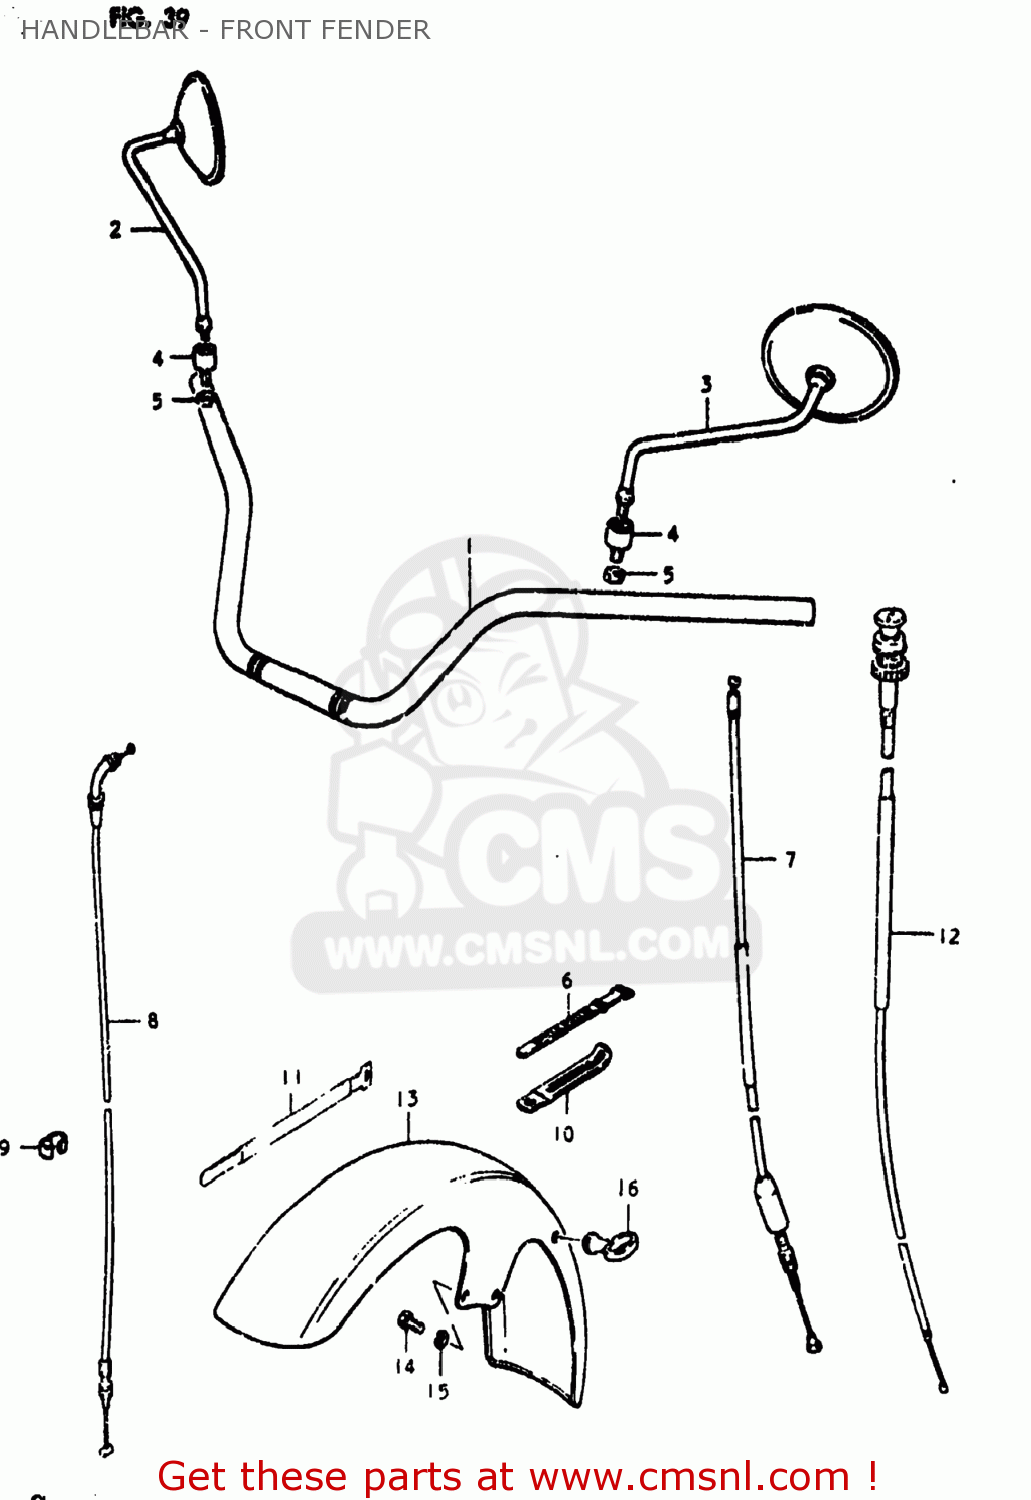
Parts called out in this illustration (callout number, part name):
1	HANDLEBAR
2	MIRROR ASSEMBLY,REAR VIEW
3	MIRROR ASSEMBLY,REAR VIEW
4	CUSHION,REAR VIEW MIRROR
5	NUT
6	CLAMP(L:120)
7	CABLE ASSY,CLUTCH
8	CABLE ASSEMBLY,THROTTLE
9	CLIP
10	CLAMP
11	CLAMP
12	CABLE ASSEMBLY,STARTER
13	FENDER ASSY,FR
14	BOLT
15	LOCK WASHER
16	GUIDE,CABLE
